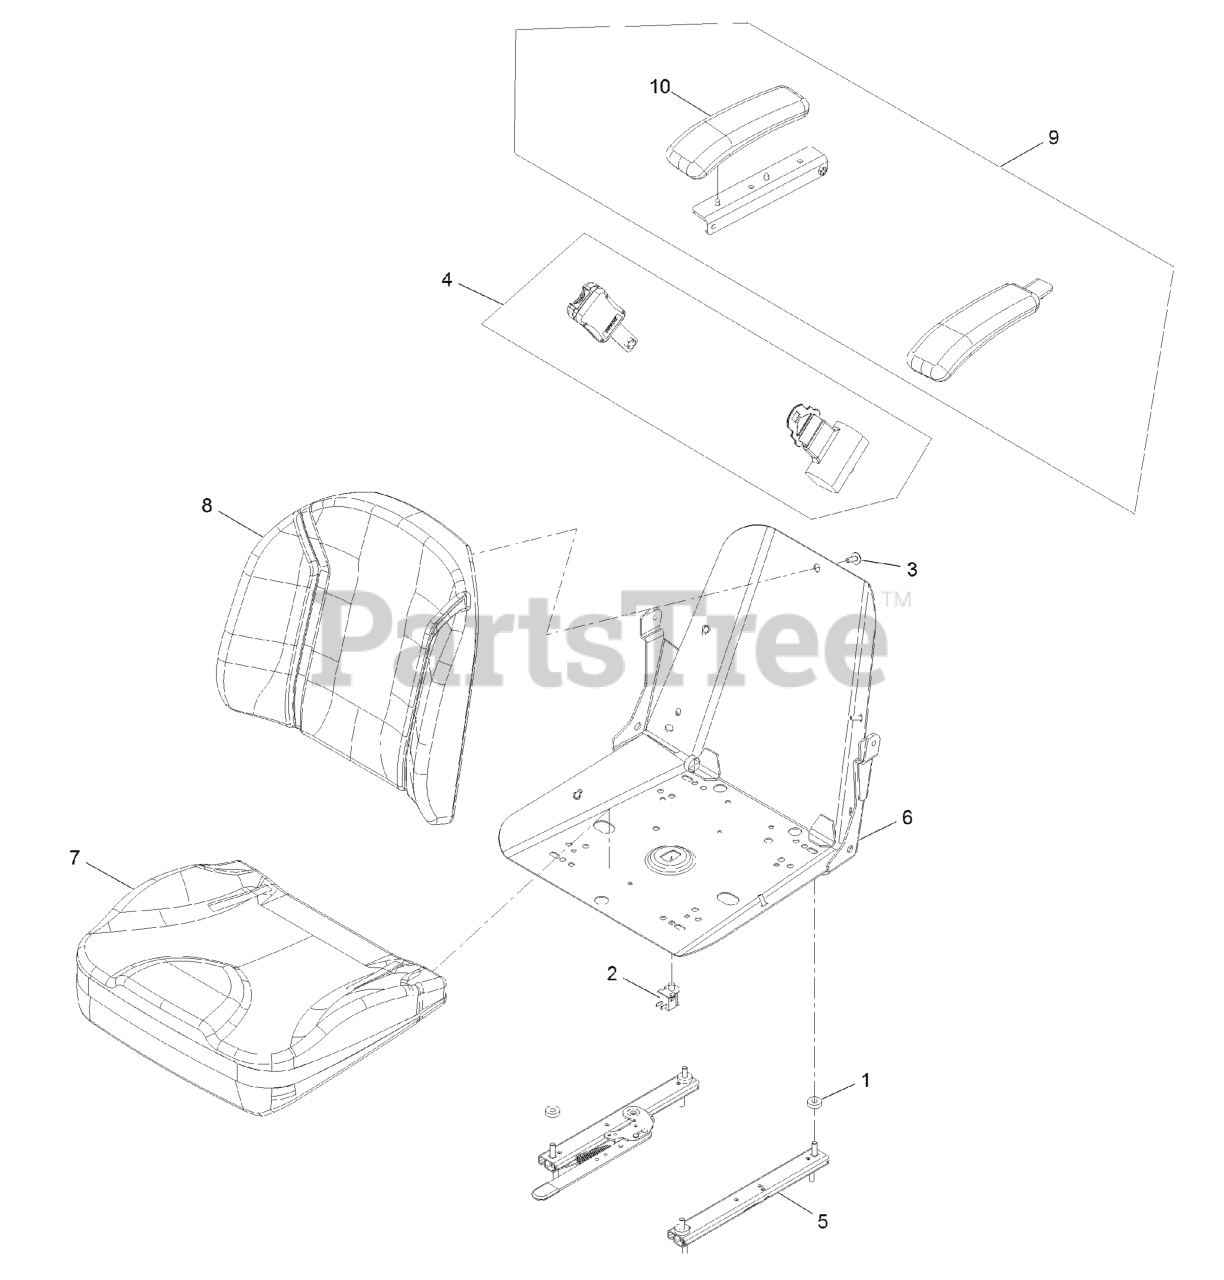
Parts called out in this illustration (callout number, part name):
2	SWITCH-BAIL
3	BOLT-SEAT
4	KIT-SEAT BELT
5	ASM-SEAT TRACK SVC
6	FRAME-SEAT SVC
7	COVER-SEAT BOTTOM SVC
8	CUSHION-SEAT, BACK
9	ARMREST KIT
10	CUSHION-REST, ARM
